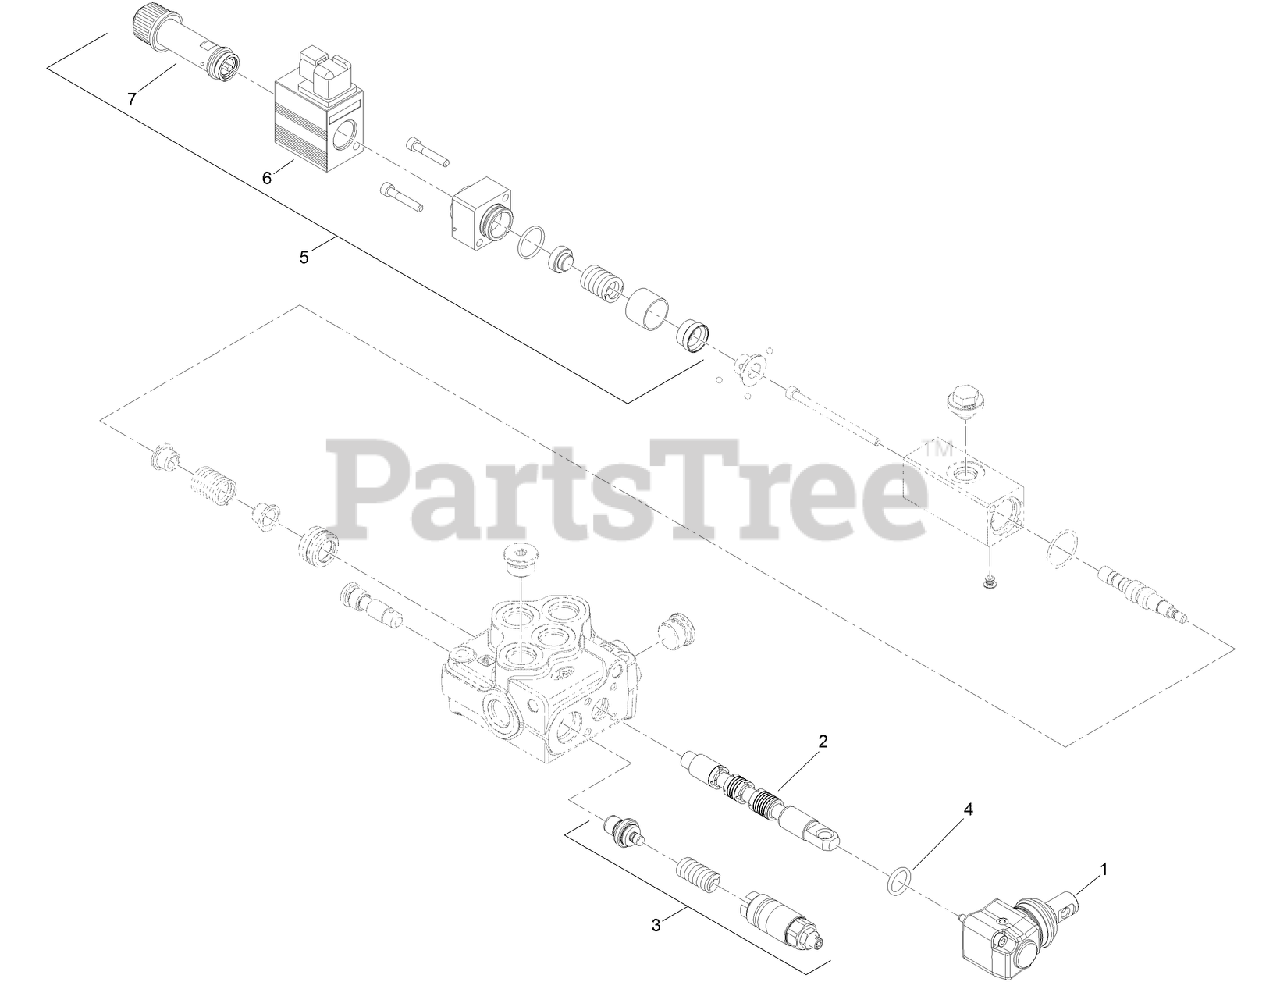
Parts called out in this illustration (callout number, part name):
1	LEVER KIT (WITH SCREWS)
2	VALVE-SPOOL
3	VALVE-RELIEF
4	SEAL-VALVE
5	SPRING/COIL VALVE KIT
6	COIL-VALVE
7	VALVE-TUBE, PULL
